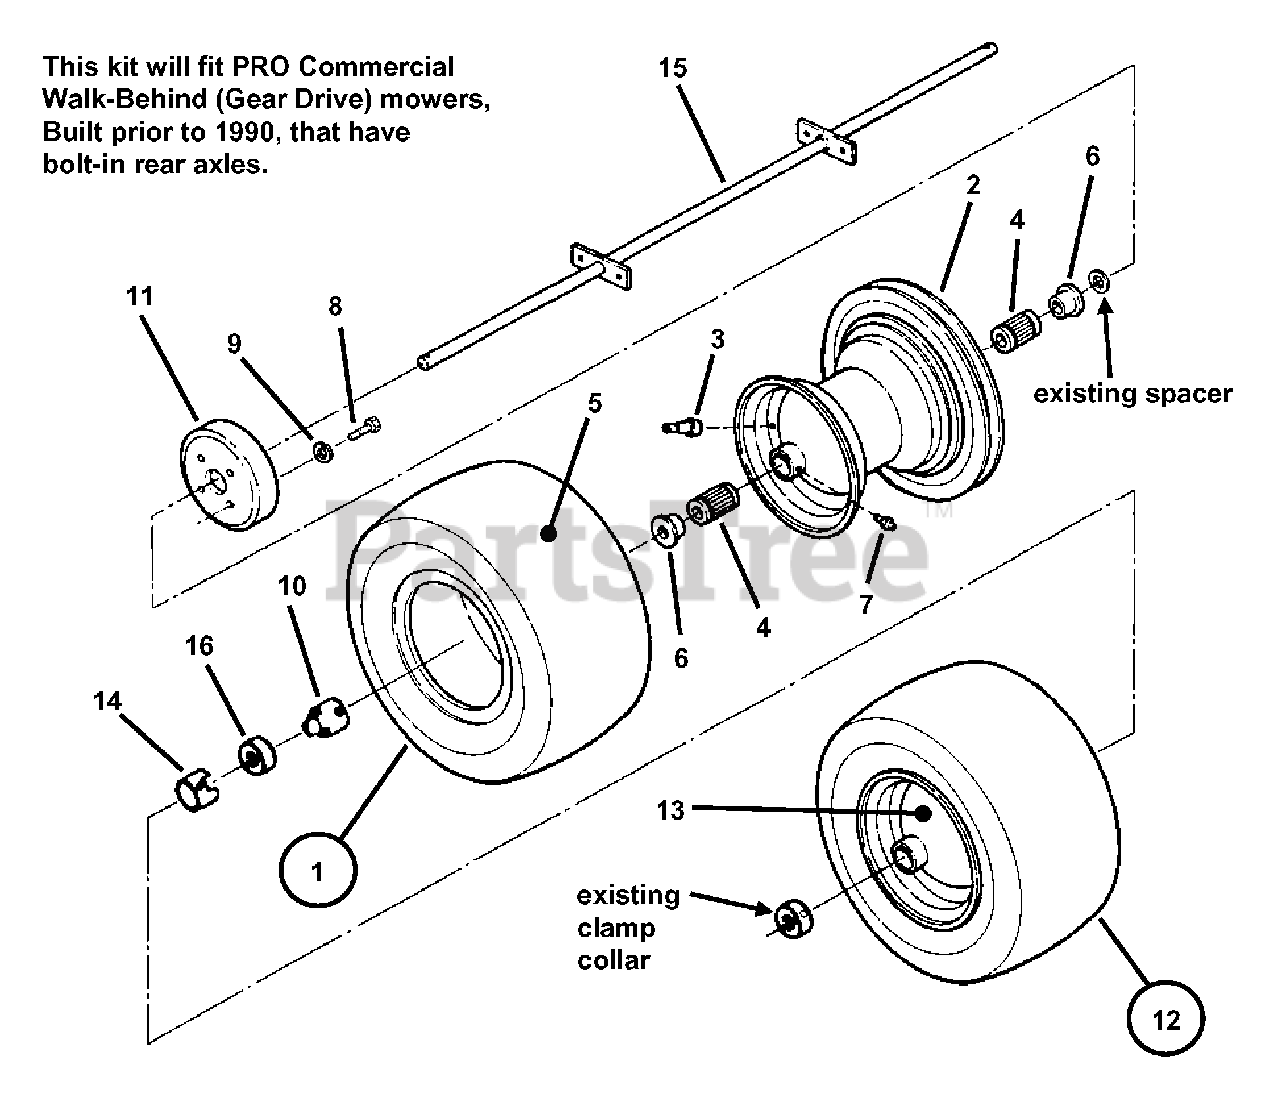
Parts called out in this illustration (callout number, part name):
1	ASSEMBLY, Drive Tire (complete, dual wheel)
2	RIM & PULLEY, Drive (dual wheel)
3	STEM, Air Valve
4	BEARING, Roller
5	TIRE, 13 x 6.50-6
6	BEARING, Flange
7	FITTING, Lube, 1/4-28, Straight
8	WASHER, 3/8" Split Lock
9	SCREW, 3/8-24 x 3/4" Hex Head Cap, Grade 5
10	COUPLING-DRIVE, Inside
11	DRUM, Brake, PTD
12	TIRE, Driven (complete, dual wheel)
13	RIM, Driven
14	COUPLING, Drive, Outside
15	WELDMENT, Rear Axle, Dual Wheel, PTD
16	SPACER, Dual Wheel
